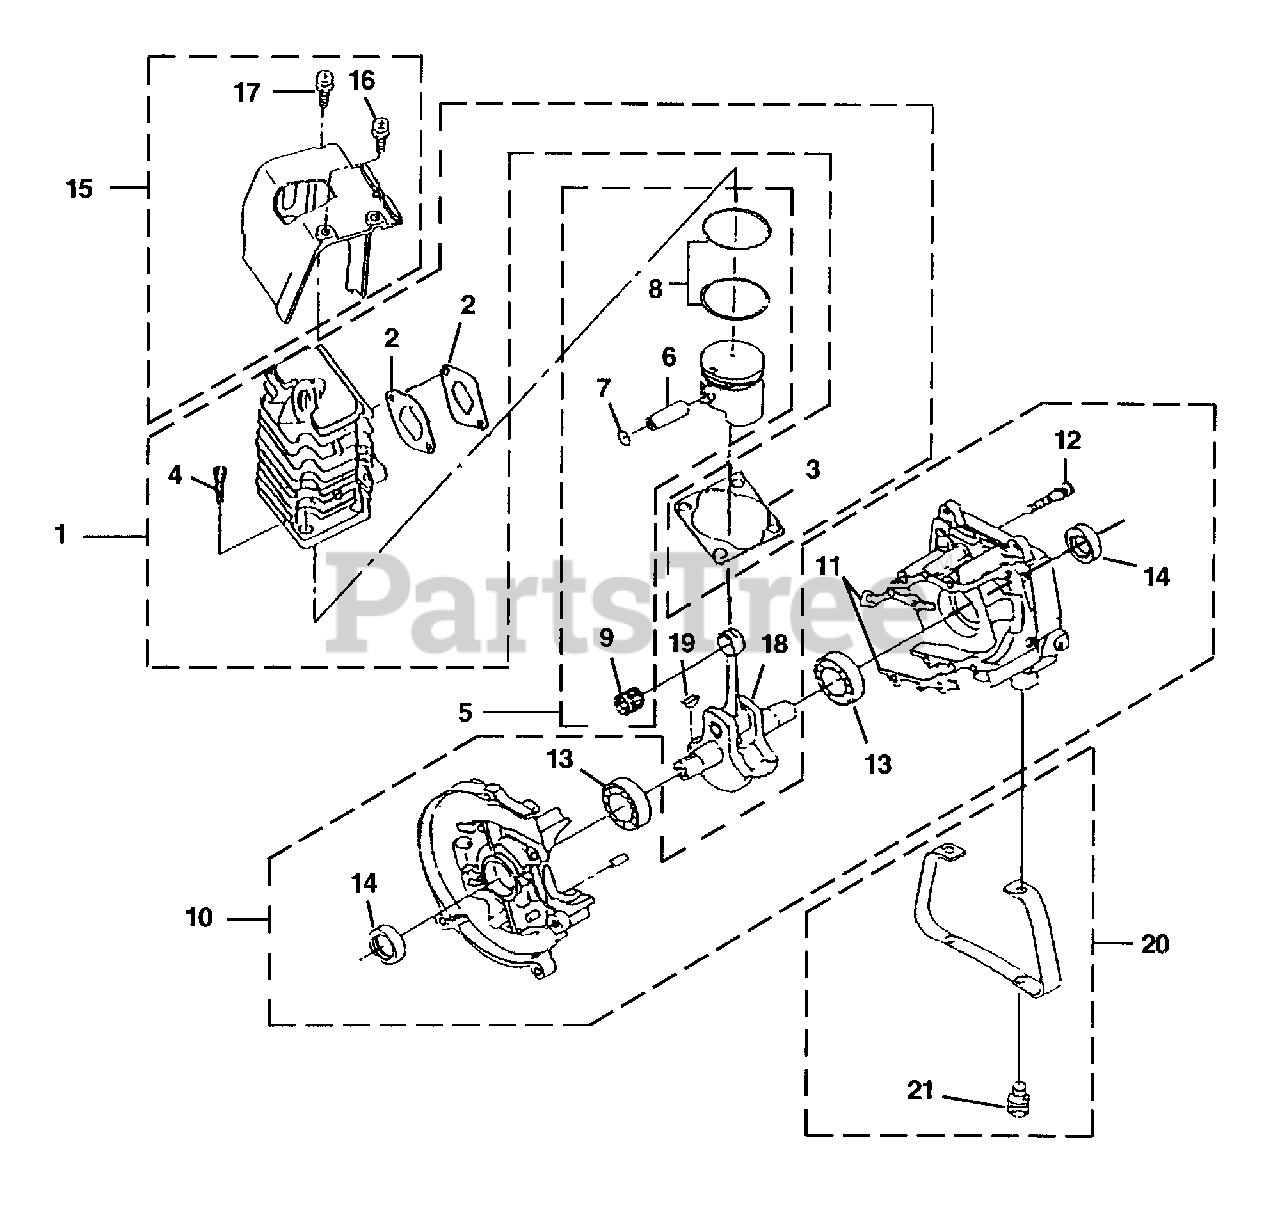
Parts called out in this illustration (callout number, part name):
1	CYLINDER ASSEMBLY
2	GASKET MUFFLER
3	GASKET-Cylinder
4	SCREW-Socket Hd (M6 X 8)
5	PISTON ASSEMBLY
6	PIN-PISTON
7	RING - Retaining
8	RING Piston
9	BEARING - Wrist Pin
10	CRANKCASE ASSY
11	GASKET-Crankcase
12	SCREW-Socket Hd (M5 x 30 SW)
13	BEARING BALL
14	OIL SEAL
15	CYLINDER COVER
16	SCREW (M5 x 14 W SW)
17	SCREW (M3 X 20W SW)
18	CRANKSHAFT
19	KEY-Woodruff
20	STAND-Engine
21	SCREW-Socket Hd (M6 X 14 SW)
